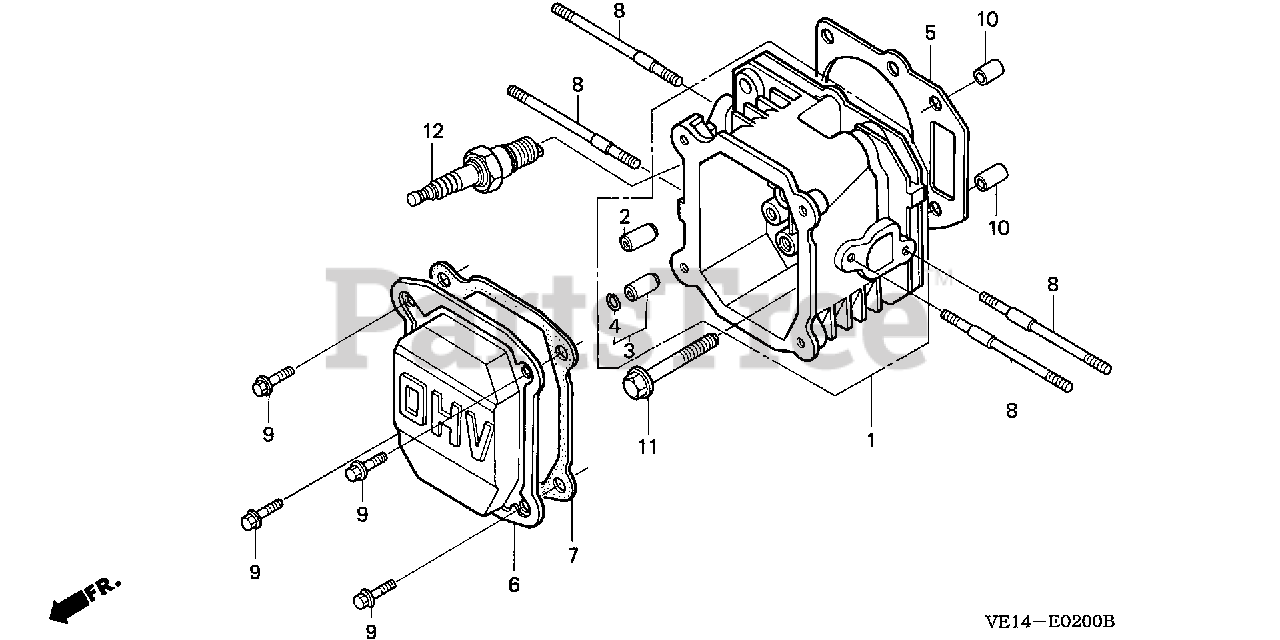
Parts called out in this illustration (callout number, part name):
1	CYLINDER HEAD (USA)
2	GUIDE, VALVE (OVER SIZE)
3	GUIDE, EX. VALVE (OVER SIZE)
4	CLIP, VALVE GUIDE
5	GASKET, CYLINDER HEAD
6	COVER, HEAD
7	GASKET, HEAD COVER
8	BOLT, STUD (6X83)
9	BOLT, FLANGE (6X14)
10	PIN, DOWEL (10X16)
11	BOLT, FLANGE (8X50)
12	SPARK PLUG (BPR4ES) (NGK)
12	SPARK PLUG (BPR5ES) (NGK)
12	SPARK PLUG (BPR6ES) (NGK)
